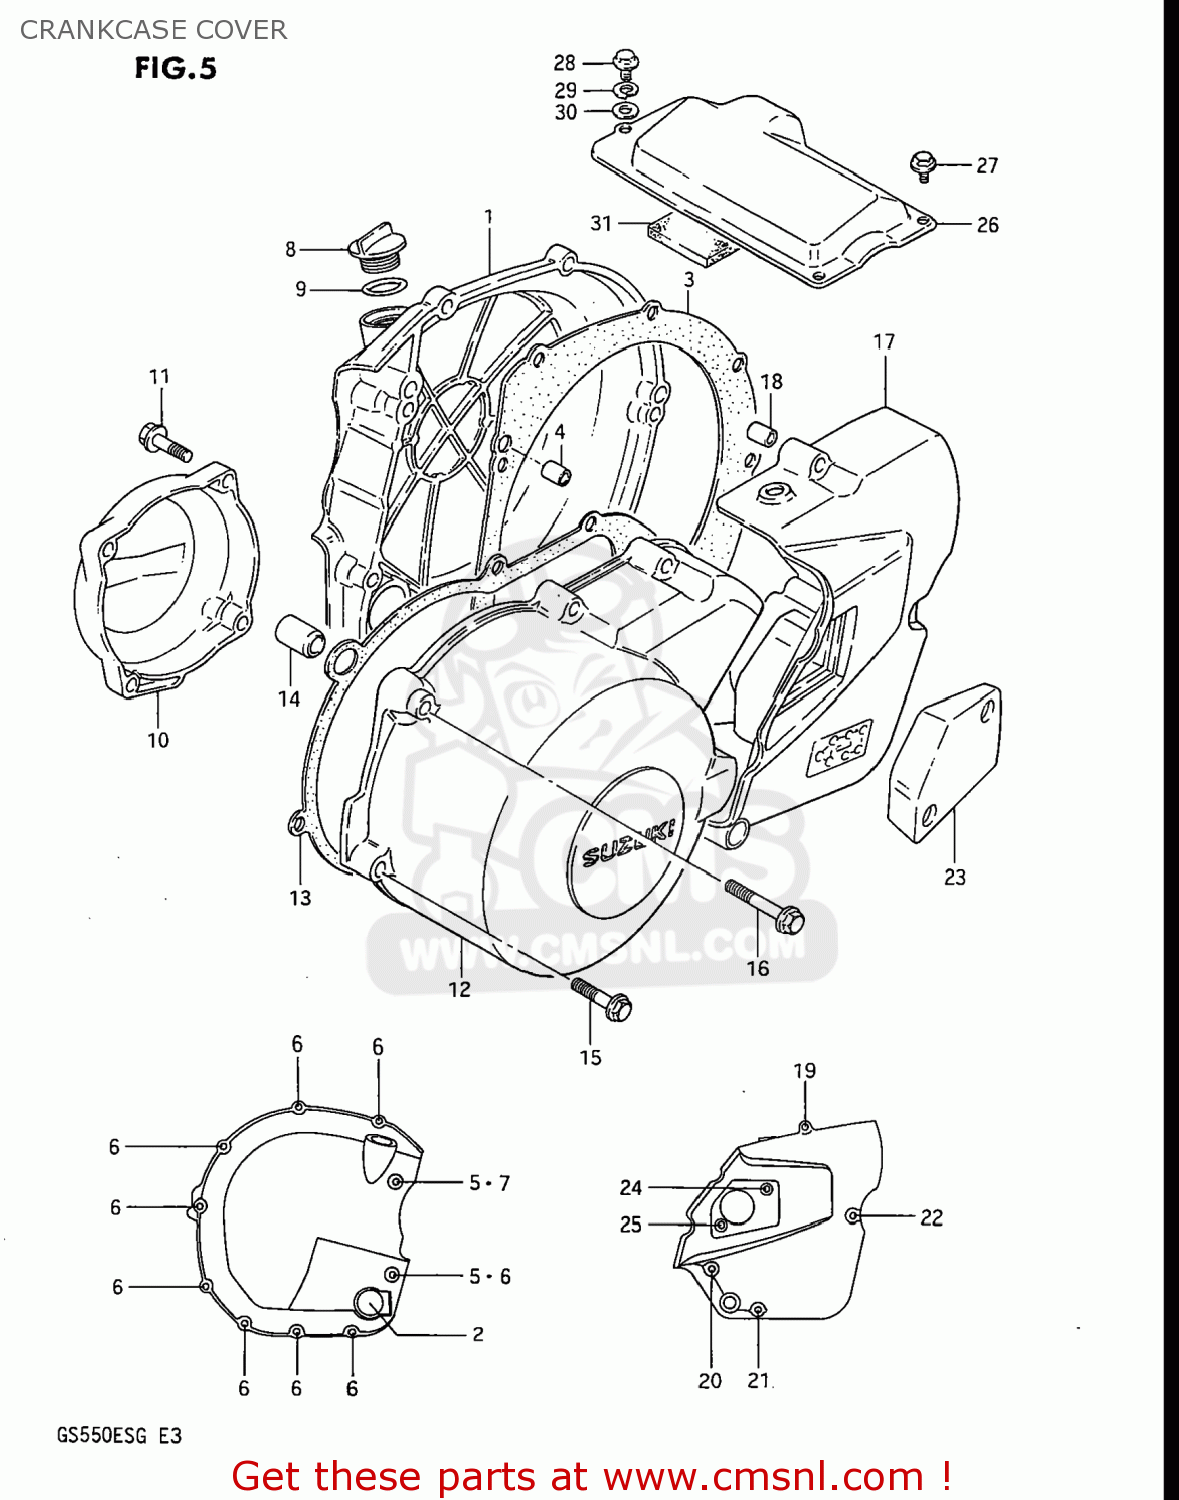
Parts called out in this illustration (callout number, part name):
1	COVER,CLUTCH
2	LENS,OIL LEVEL CHECK
3	GASKET,CLUTCH COVER (MCA)
4	PIN
5	WASHER
6	BOLT 6X25
7	BOLT 6X35
8	PLUG
9	O RING(D:3.1,ID:16.8)
10	COVER,CONTACT BREAKER
11	BOLT 6X25
12	COVER,MAGNETO
13	GASKET,MAGNETO COVER (MCA)
14	PIN (11X20)(SUS)
15	BOLT 6X30
16	BOLT
17	COVER,ENGINE SPROCKET
18	PIN
19	BOLT 6X40
20	BOLT (6X55)
21	BOLT 6X50
22	BOLT 6X80
23	CAP,CLUTCH RELEASE ADJUST
24	SCREW
25	SCREW
26	COVER,STARTER MOTOR
27	BOLT
28	BOLT
29	WASHER,LOCK
30	WASHER
31	DAMPER,STARTER MOTOR CLUTCH
